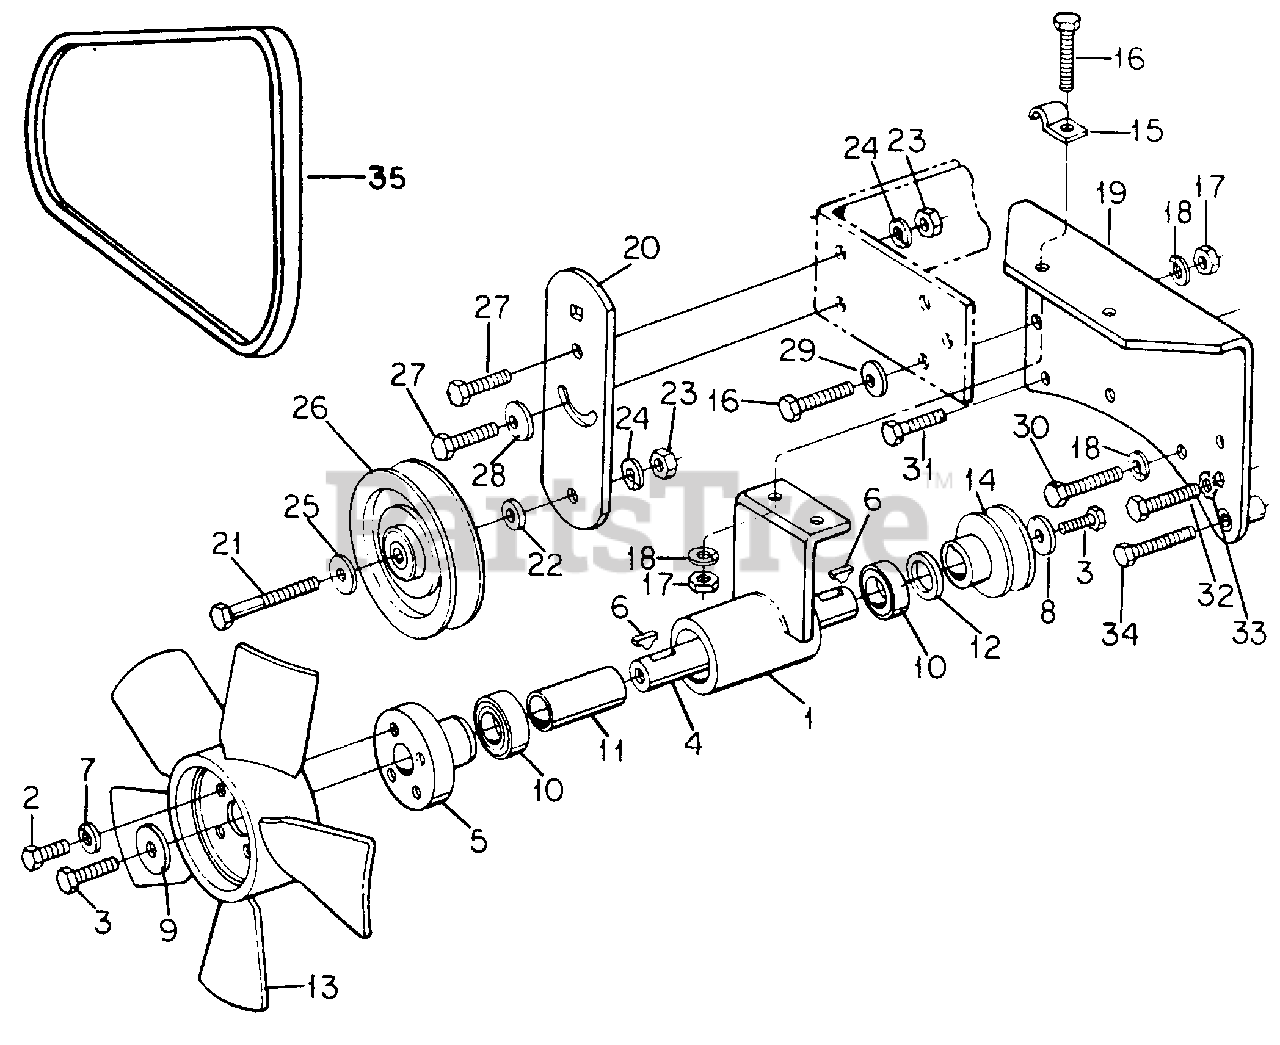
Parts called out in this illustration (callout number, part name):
1	Support, Fan
2	Bolt, 1/4 X 5/8 Type 5
3	Bolt, Hex Patch, 5/16 X 1-1/8
4	Shaft, Fan
6	Key, Special
7	Washer, 1/4 Lock
10	Bearing, Ball
15	Clip, Cable
16	Bolt, 5/16-NF X 1 Type 5
17	Nut, 5/16-NF Type 5
18	Washer, 5/16 Lock
19	Bracket, Fan Mount
20	Bracket, Idler Support
21	Bolt, 3/8 X 1-3/4 Type 5
23	Nut, 3/8 Cad P/T Lock Type 5
24	Washer, 3/8 Lock
25	Washer, .406 X .812 X .051
26	Pulley, Idler
27	Bolt, 3/8 X 1 Type 5
28	Washer, Bell
29	Washer, Bell
30	Bolt, M8 X 40 Phc Class 8.8
31	Bolt, 5/16-NF X 2 Type 5
32	Bolt, 5/16 X 1-1/4 Type 5
33	Washer, 5/16 Ext-Int Tooth Lock
34	Bolt, 5/16-NF X 1-1/2 Type 5
35	Belt, Fan
